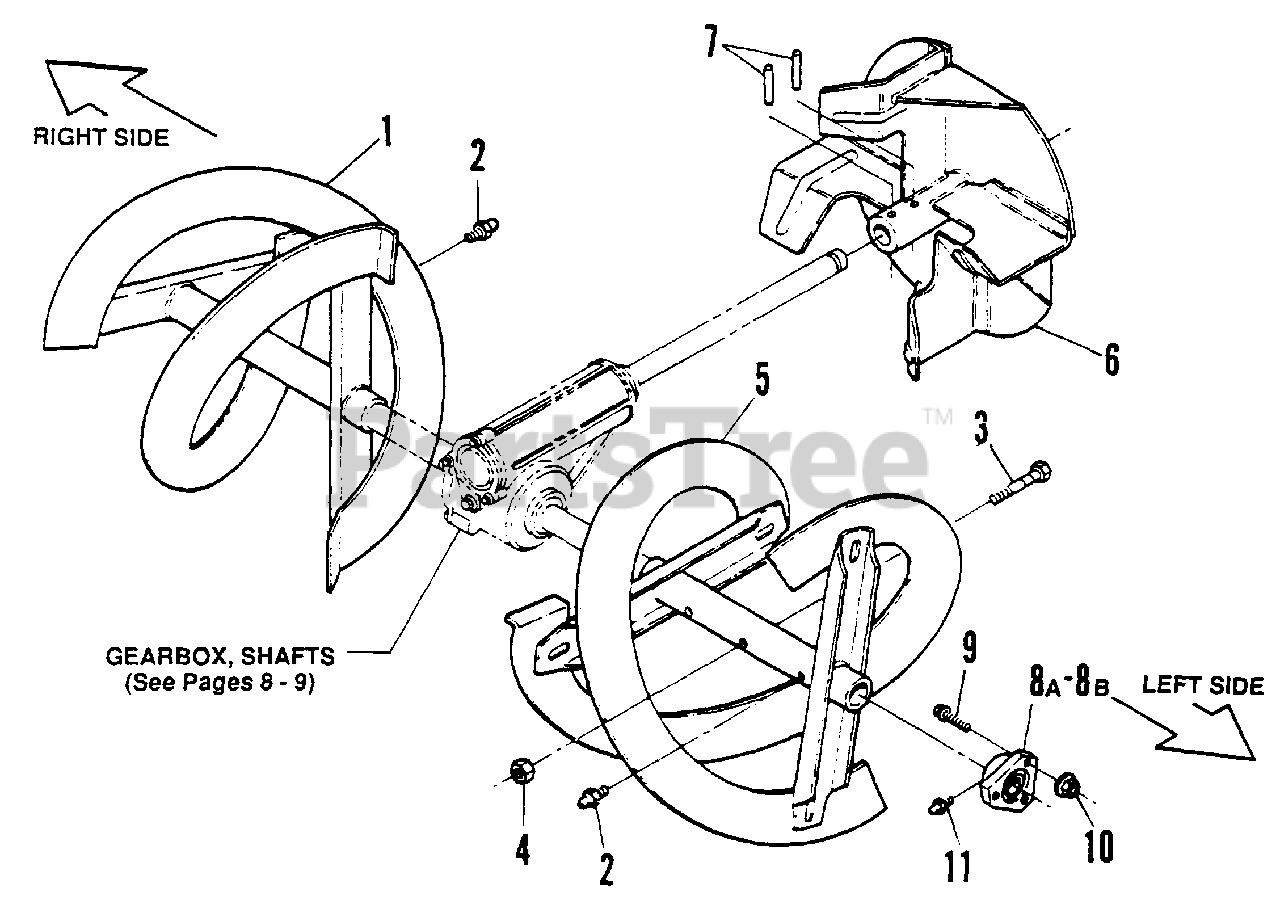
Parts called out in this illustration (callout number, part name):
1	AUGER, Right Side
2	LUBE FITTING, Straight (press-fit for .187 dia. Hole)
3	BOLT, 5/16-18 x 1-7/8" Shear
4	NUT, 5/16-18 Hex Center Lock
5	AUGER, Left Side
6	FAN, Impeller
7	PIN, 1/4 x 1-1/2" Roll
8A	ASSEMBLY, Bearing
8B	ASSEMBLY, Bearing
9	BOLT, 1/4-20 x 1-1/8" Hex Flange Lock
10	NUT, 1/4-20 Hex Flange Lock
11	FITTING, Lube (Press fit for .187 hole-no ball)
